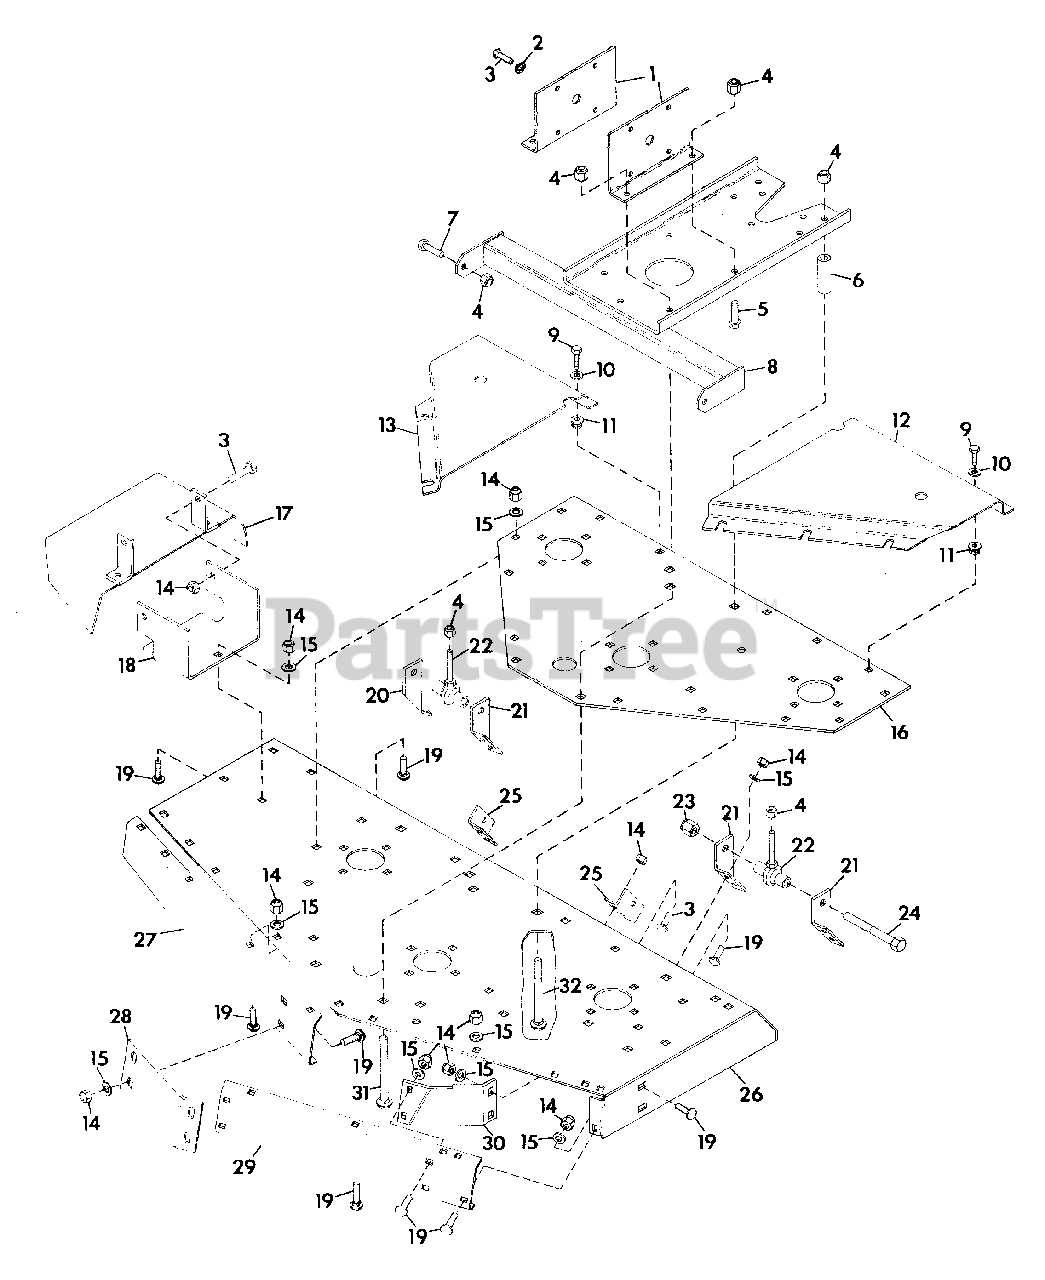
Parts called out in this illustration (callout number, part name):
1	PLATE, GEARBOX SUPPORT
2	WASHER, LOCK 3/8 REG.
3	BOLT, HEX 3/8-16X1.00
4	NUT, LOCK 1/2-13
5	BOLT, HEX 1/2-13X1.25
6	SPACER, .850X.546X2.18
7	BOLT, HEX 1/2-13X1.375
8	WELDMENT, SUPPORT PLATE
9	BOLT, HEX 1/4-20X.625
10	WASHER, FLAT .281X.625X.065
11	GROMMET, PLASTIC
12	COVER, BELT L.H.
13	COVER, BELT R.H.
14	NUT, LOCK 3/8-16
15	WASHER, FLAT .406X.812X.065
16	PLATE, DECK SUPPORT
17	WELDMENT, DISCHARGE CHUTE
18	BRACKET, DISCHARGE
19	BOLT, 3/8-16X1.00 RD HD SQ NK
20	PLATE, REAR ADJUSTMENT
21	PLATE, REAR ADJUSTMENT
22	ROD, END
23	NUT, LOCK 3/4-10
24	BOLT, HEX 3/4-10X3.50
25	BRACKET, LIFT
26	WELDMENT, 60" OFC
27	PLATE, FRONT COVER
28	BRACKET, FRONT DECK
29	PLATE, FRONT COVER L.H.
30	BAFFLE, FRONT
31	BOLT, 1/2-13X3.75 RD HD SQ NK
32	BOLT, 1/2-13X3.50 RD HD SQ NK
